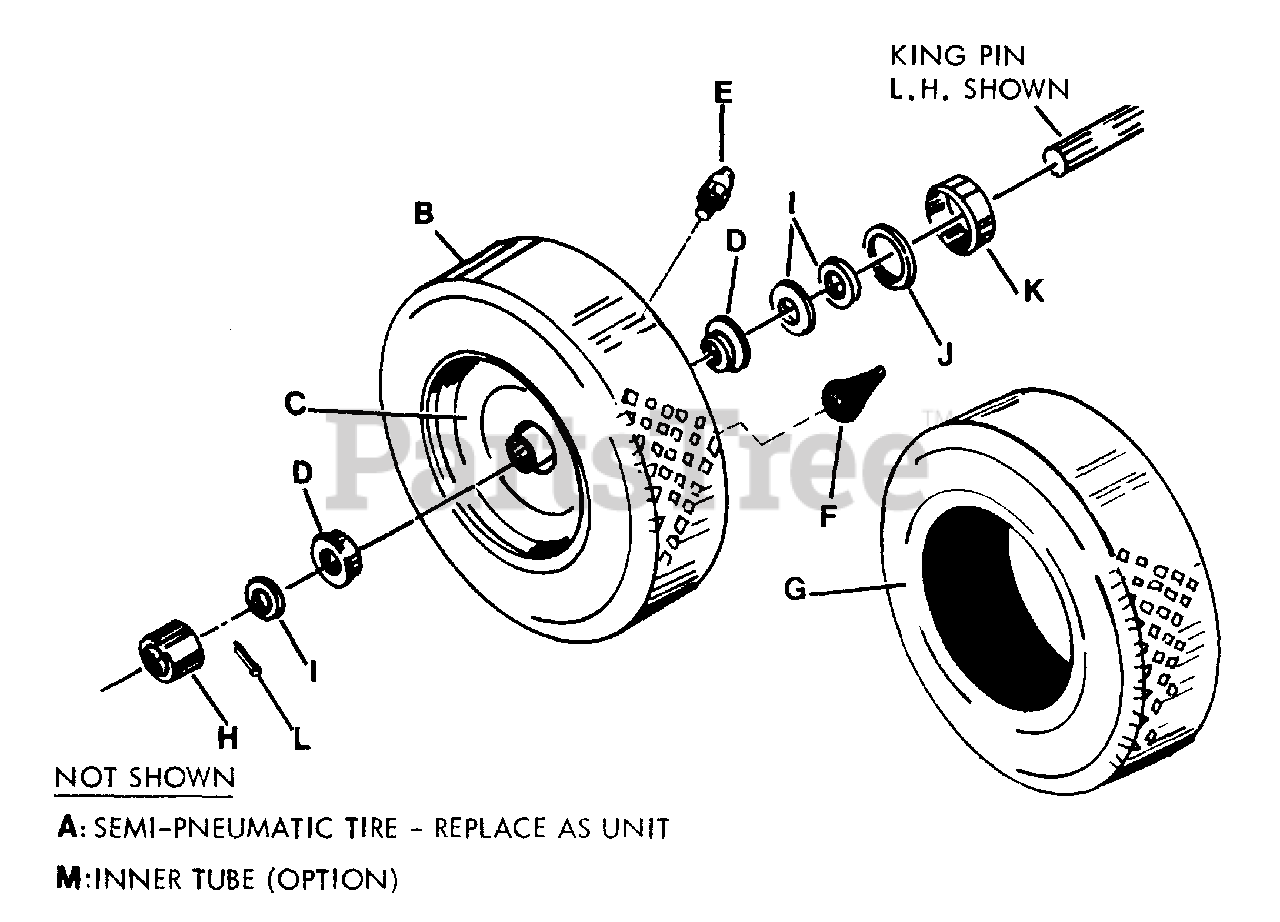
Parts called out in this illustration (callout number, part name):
A	WHEEL/TIRE ASSEMBLY
B	ASSEMBLY, Tire & Rim
C	RIM, (For 4.10/3.50x4 Tire)
D	BEARING, BALL (2)
E	LUBE Fitting, 90 Degree, Ball Check (for 1/4" hole)
F	STEM, VALVE
G	TIRE, 4.10 - 3.50 x 4
H	CAP, FRONT WHEEL HUB
I	WASHER
J	WASHER, FELT
K	CAP, DUST
L	COTTER-PIN 5/32 x 1"
